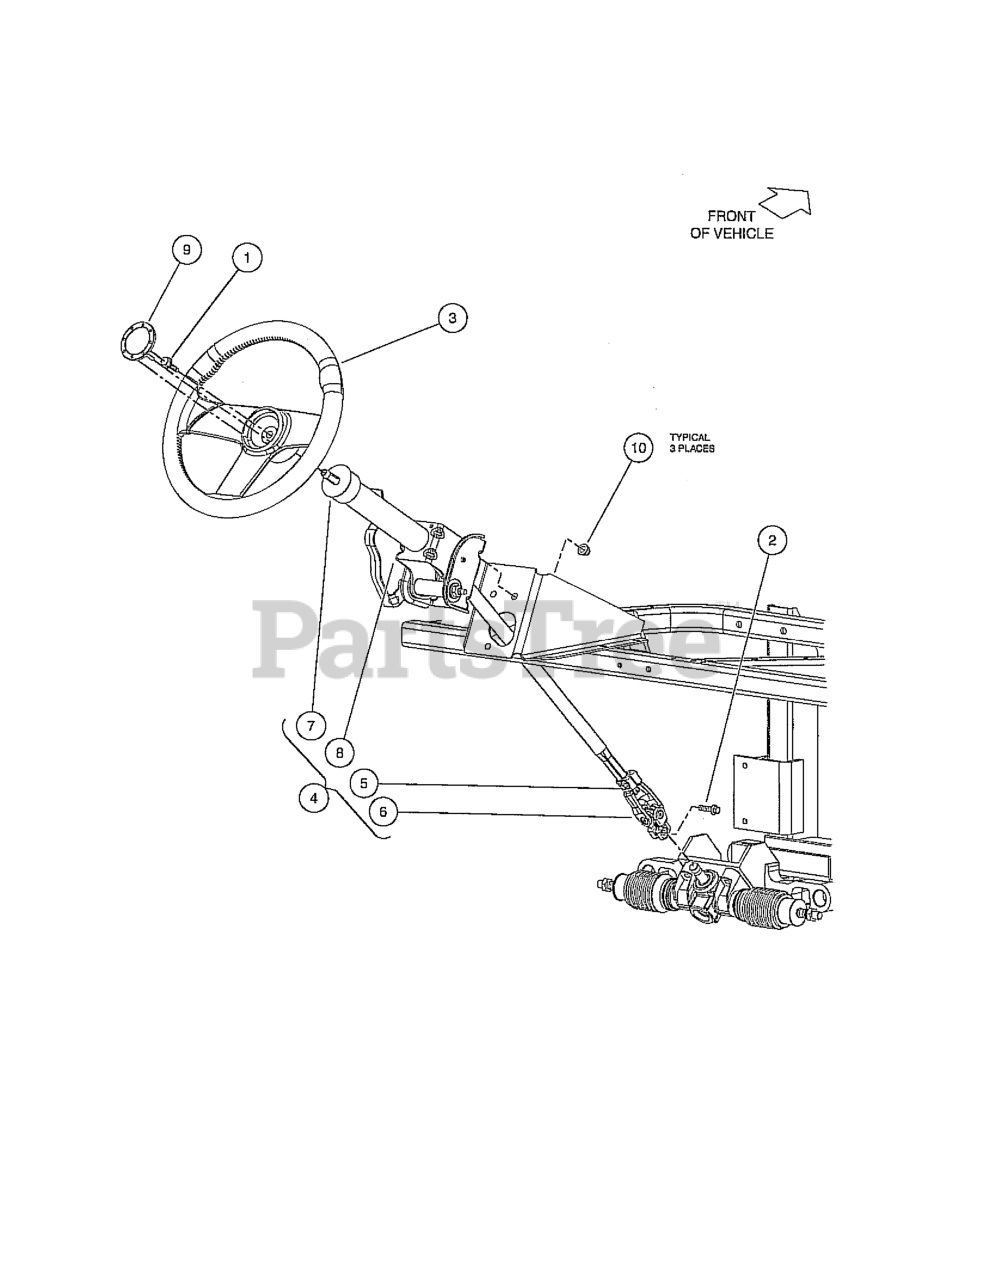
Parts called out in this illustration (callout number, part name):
1	BOLT, M10 X 20 HEX WASHER HD
2	BOLT - FLANGED HD, M8 X 30.0
3	STEERING WHEEL, VIPER, HEX HUB
4	STEERING COLUMN
5	BOLT - FLANGED HD, M8 X 30.0
9	CAP, STEERING WHEEL, VIPER
10	LOCK NUT, FLG M8 X 1.25 NYLON
